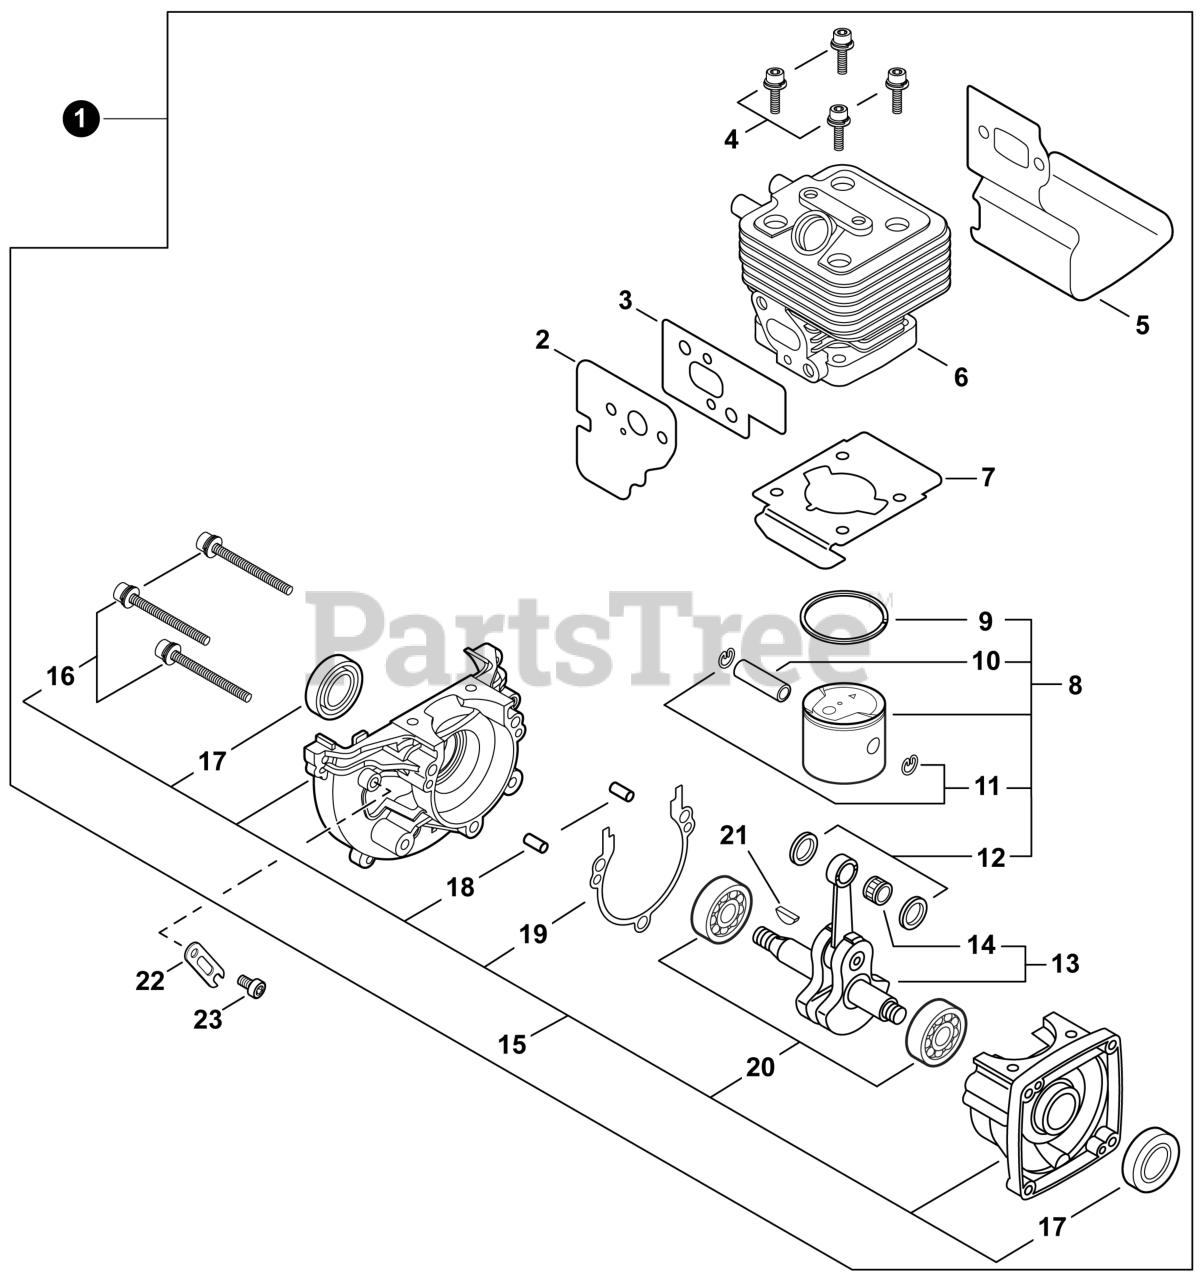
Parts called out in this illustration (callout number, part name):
1	SHORT BLOCK
2	GASKET, INTAKE
3	GASKET, INTAKE
4	BOLT 5x25
5	HEAT SHIELD, EXHAUST
6	CYLINDER
7	GASKET, CYLINDER
8	PISTON KIT
9	RING, PISTON
10	PIN, PISTON
11	RING, SNAP
12	WASHER, THRUST
13	CRANKSHAFT ASSY
14	BEARING, NEEDLE 8
15	CRANKCASE KIT
16	BOLT 5x28
17	SEAL, OIL 12
18	PIN, LOCATING 4x8
19	GASKET, CRANKCASE
20	BEARING, BALL 6201
21	KEY, WOODRUFF
22	PLATE, EYE
23	BOLT, TORX 5x8
